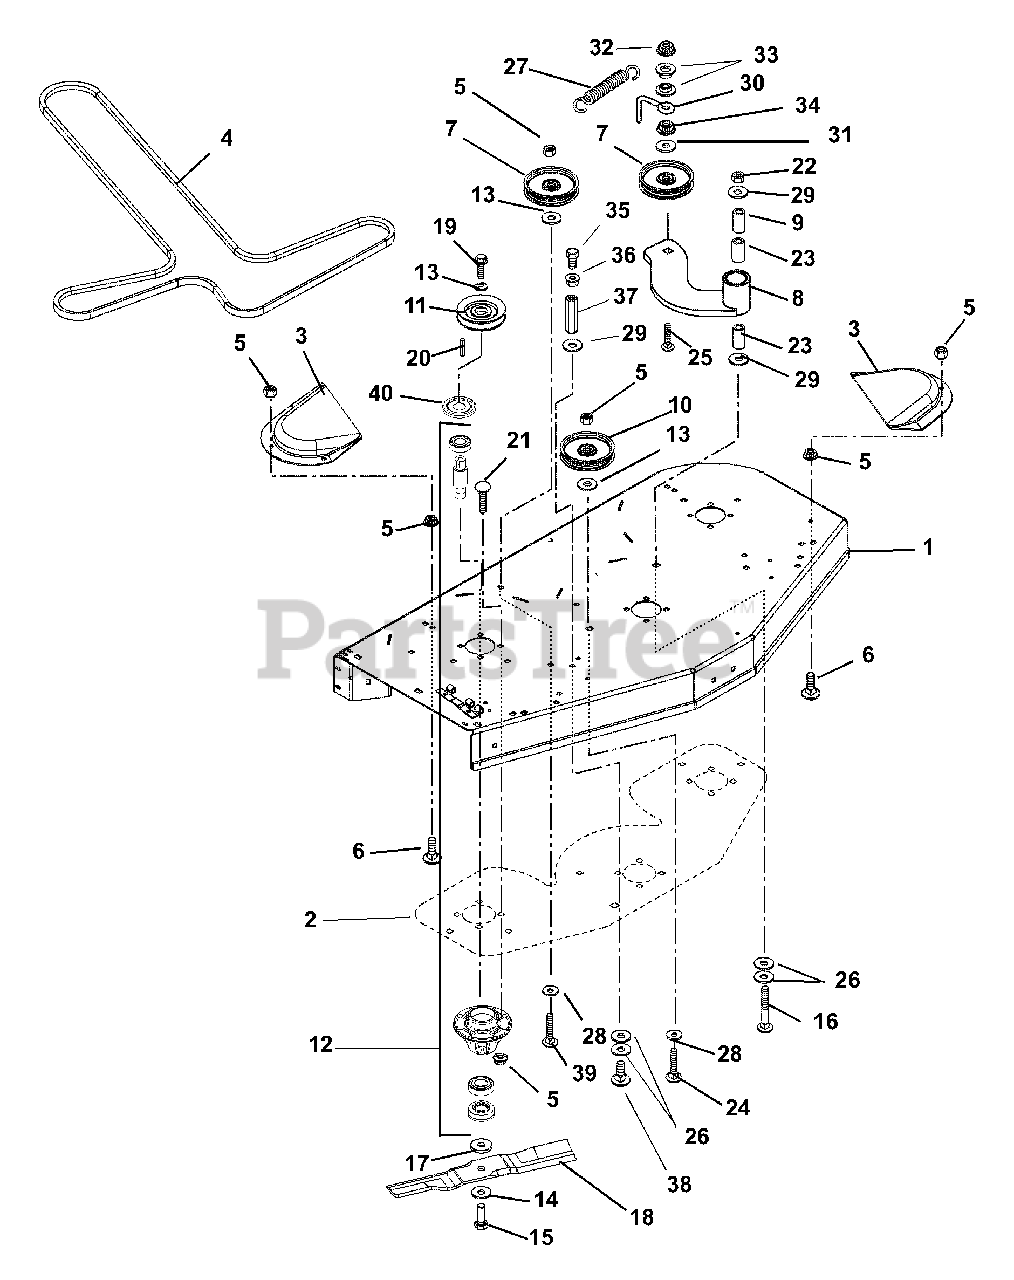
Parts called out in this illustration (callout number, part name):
1	40" Mower Deck
1	44" Mower Deck
1	48" Mower Deck
1	52" Mower Deck
2	Plate, 40" Doubler
4	V-Belt
5	Nut .38-16 Flange Nyloc
6	Bolt, Round Head Square Neck .38-16 x 1.25 Grade 5
7	Idler, Flat .38 x 4.00 x 1.06
8	Weldment, Idler Arm
9	Spacer, Powdered Metal
10	Pulley, Idler 4.00
11	Sheave, Spindle 4.00 Dia.
11	Sheave, Spindle 4.25 Dia.
11	Sheave, Spindle 4.50 Diameter
11	Sheave, Spindle 4.25 Diameter
11	Sheave, Spindle 4.75 Diameter
12	Assembly, Spindle
13	Washer, Flat Steel .406 x 1.50 x .245
14	Washer, Bellville .63 x 1.625 x .140
15	Bolt, Hex .62-18 x 1.75 Grade 8
16	Bolt, Round Head Square Neck .50-13 x 3.50 Grade 5
17	Washer, Flat .64 x 1.81 x .25
18	Blade, Mower
19	Bolt, Hex .38-16 x 1.00 Grade 8 with Epoxy Patch
20	Key, Square .25 x .38 x .25
21	Bolt, Round Head Square Neck .38-16 x 1.50
22	Nut, Locking Top Flange .50-13
23	Bearing, 1.00 x 1.12 x .75
24	Bolt, Round Head Square Neck .38-16 x 2.00 Grade 5
25	Bolt, Round Head Square Neck .38-16 x 3.00 Grade 5
26	Washer, Flat Steel .755 x 1.375 x .062
27	Spring, Extension
28	Washer, Flat Steel .563 x 1.38 x .109
29	Washer, Flat Steel .515 x 1.625 x .25
30	Finger, Belt
31	Washer, Flat Steel .406 x 1.00 x .188
32	Nut, Locking Top Flange .38-16
33	Bushing, Sleeve .752 x .877 x .75 Bronze
34	Nut, Spiral Lock Flange .50-13
35	Bolt, Hex .50-13 x 2.00 Grade 5
36	Nut, Hex .50-13
37	Coupling .50-13 x 1.75
38	Bolt, Round Head Square Neck .50-13 x 1.25 Grade 5
39	Bolt, Round Head Square Neck .38-16 x 2.75 Grade 5
40	Cap, Dust
